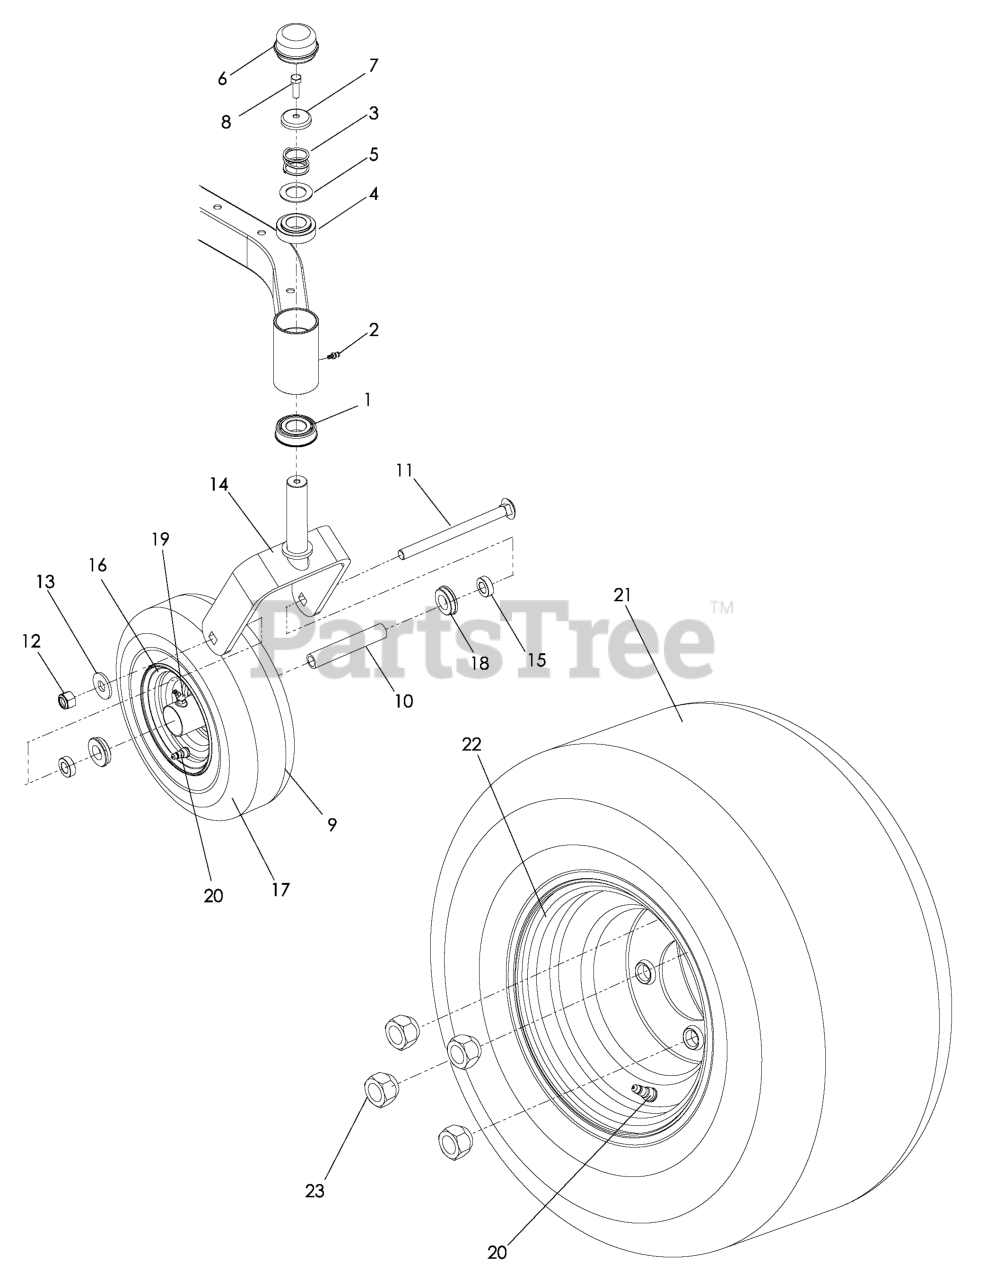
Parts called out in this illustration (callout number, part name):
1	BEARING, FLANGED
2	ZERK 3/16 DRIVE
3	SPRING, CASTER
4	BUSHING, CASTER
6	GREASE CAP
7	PLUG, CASTER
8	HCS 5/16-18 x 1
9	CASTER TIRE ASSM Items 16-20
11	RHSNB ½-13 x 6½
12	NUT ½-13 HEX NYLOC
13	WASHER ½ FLAT
14	YOKE
15	SPACER 5/16
17	CASTER TIRE, 410/350 4 PLY
18	BEARING, FLANGED
19	ZERK
20	VALVE STEM
21	TIRE ASSEM, REAR 18 x 8.5 968881201, 965921501,
22	RIM, 8 x 7 968881201, 965921501
23	NUT, LUG ½-20 HEX
